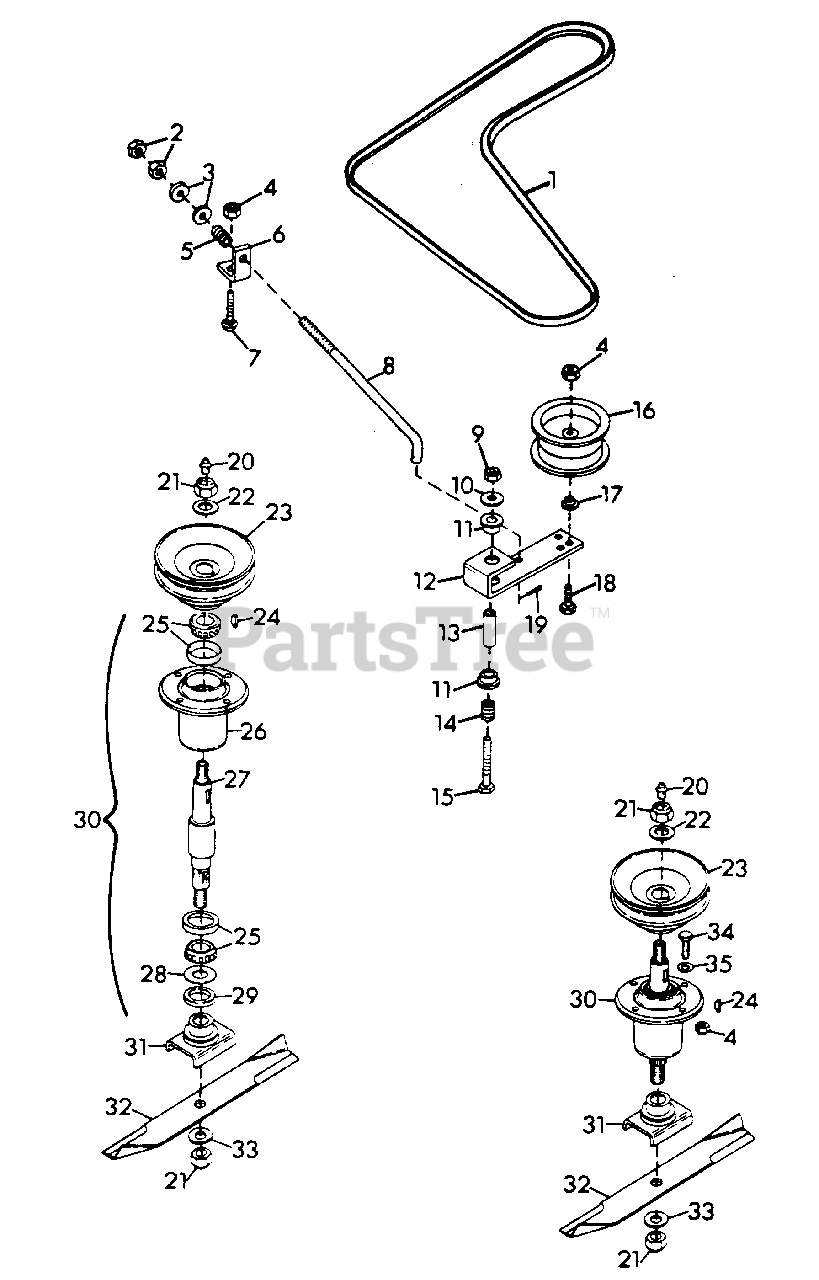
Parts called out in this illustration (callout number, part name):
1	Belt, Pro-36 Mower
2	Nut, Hex 3/8-24
3	Washer, Flat .406x.812x.065
4	Nut, Lock 3/8-16
5	Spring, Compression 1x.78x338
6	Bracket, Belt Tensioner
7	Bolt, 3/8-16x1.00 Rd Hd Sq Nk
8	Rod, Idler
9	Nut, Lock 1/2-13
10	Washer, Flat .531x1.250x.100
11	Bushing, Nylon .76x1.00x.600 Flg.
12	Arm, Idler Pivot
13	Spacer
14	Spring, Compression 1x.80x36
15	Bolt, Hex 1/2-13x3.25
16	Pulley, Idler
17	Bushing
18	Bolt, Hex 3/8-16x2.25
19	Pin, Cotter .09x.75
20	Fitting, Lube 1/8
21	Nut, Lock 5/8-11
22	Washer, Flat .687x1.312x.122
23	Sheave, Spindle
24	Key, Woodruff 1/4x1 Hard #15
25	Assembly, Bearing
26	Housing, Bearing
27	Shaft, Spindle
28	Washer, Flat .975x1.970x.030
29	Seal, Steel
30	Assembly, Spindle
31	Weldment, Blade Cradle
32	Blade, 36" Mower
33	Washer, Flat .656x1.312x.095
34	Bolt, Hex 3/8-16x1.25
35	Washer, Flat .438x1.00x.083
